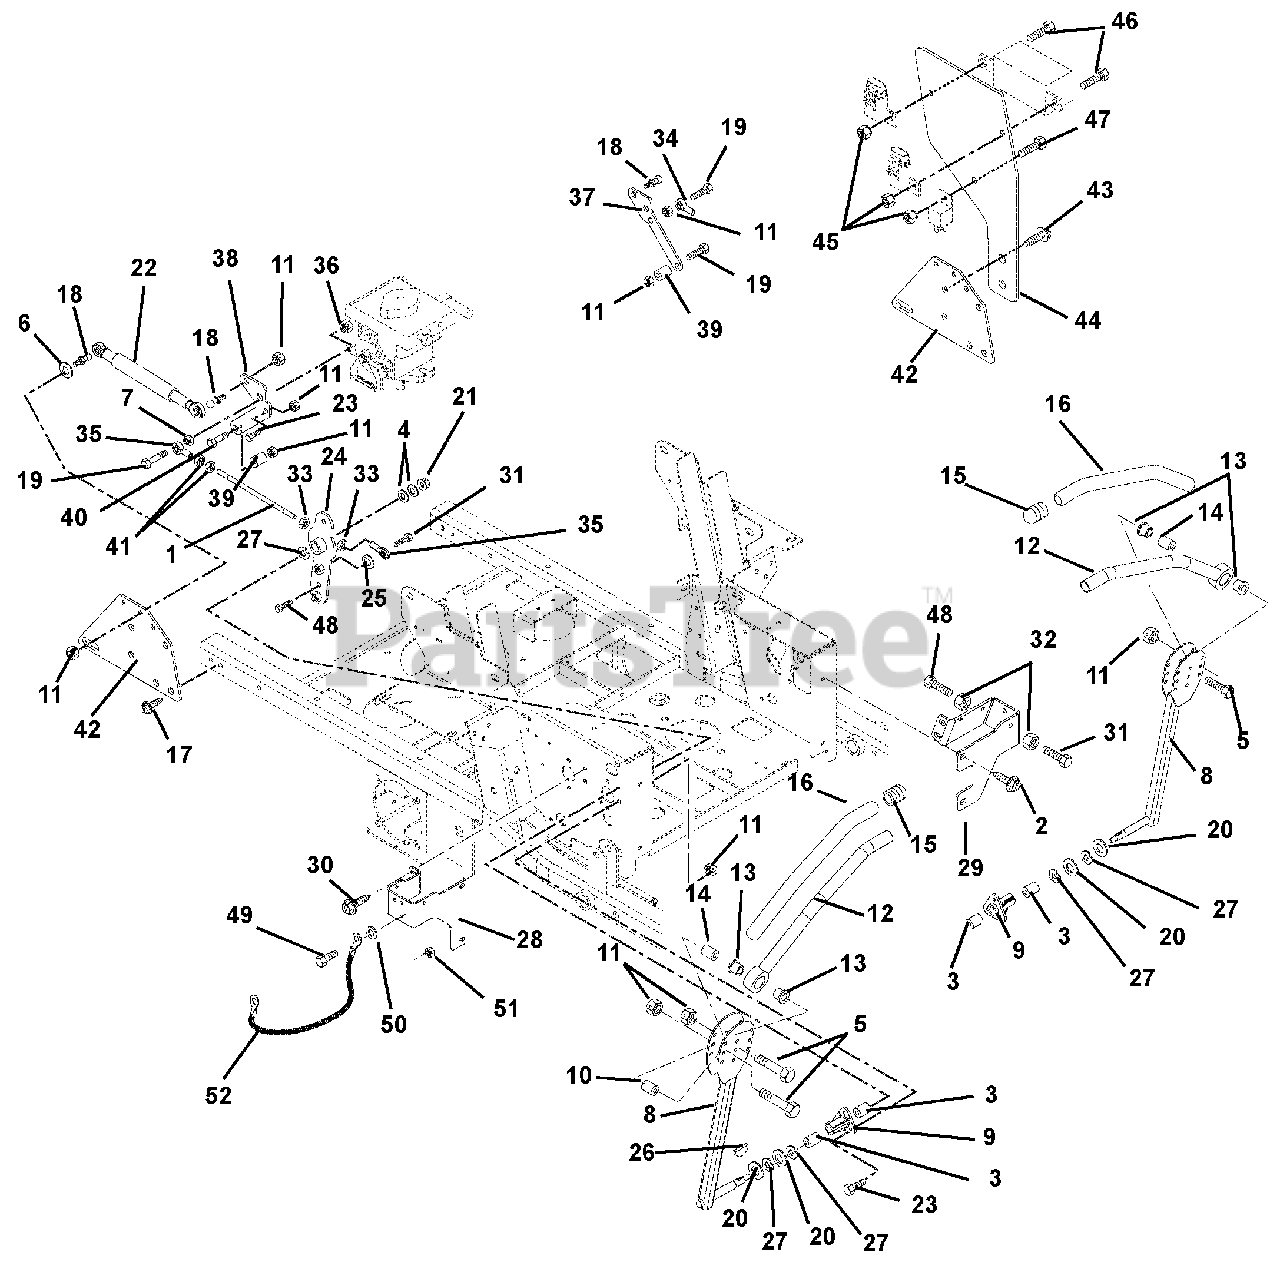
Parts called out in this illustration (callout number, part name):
1	Rod, Steering Adjustment
2	Screw, Tapping .38-16 x .75 Hex Washer Head
3	Bushing .625 x .75 x .50
4	Washer, Flat Steel .403 x .812 x .065
5	Bolt, Hex .31-18 x 1.75 Grade 5
6	Washer, Flat Steel .344 x .688 x .065
7	Nut, Hex .38-16
8	Control Arm
9	Bushing, Flange
10	Eccentric
11	Nut, Locking Top Flange .31-18
12	Handle Weldment Left-Hand
13	Bushing, Flange Nylon .762 x 1.48 x .44
15	Caplug, Handlebar
16	Grip, Handlebar
17	Screw, Tapping .31-18 x .50 Hex Washer Head
18	Stud, Ball
19	Bolt, Hex .38-16 x 1.50 Grade 5
20	Washer, Flat Steel .63 x 1.005 x .062
21	Nut, Locking Top Flange .38-16
22	Damper, Control
23	Bolt, Hex .31-18 x .75 Grade 5
24	Weldment, Pivot Arm
25	Washer, Locking .38 x .094 Regular
26	Key, Woodruff .13 x .63
27	Washer, Wave
28	Stop, Steering Right Hand
29	Stop, Steering Left Hand
30	Screw, Tapping .38-16 x .50 Hex Washer Head
31	Bolt, Hex .38-16 x 1.25 Grade 5
32	Nut, Hex Jam .375-16
33	Nut, Jam .375-24 Left Hand
34	Rod End, .38 Right Hand
35	Rod End, .38 Left Hand
36	Nut, Locking Center .38-16
37	Bracket, Left Hand
38	Bracket, Right Hand
39	Spacer .318 x .43 x .375
40	Bolt, Hex .31-18 x 1.25 Grade 5
41	Nut, Jam .375-24
42	Bracket, Damper
43	Screw, Tapping .38-16 x .50 Hex Washer Head (091, 107)
44	Bracket, EFI Box Mount (091, 107)
45	Nut, Locking Nylon 10-24 with Insert (091, 107)
46	Screw, Machine 10-24 x 2.00 Hex Washer Head (091, 107)
47	Screw, Machine 10-24 x .50 Hex Washer Head (091, 107)
48	Bolt-Hex .375-16 x 1.75 Full Thread
49	Bolt-Hex .25-20 x .75 Grade 5
50	Washer, Flat Steel .265 x .50 x .087
51	Nut, Locking Top Flange .25-20
52	Cable, Hood
